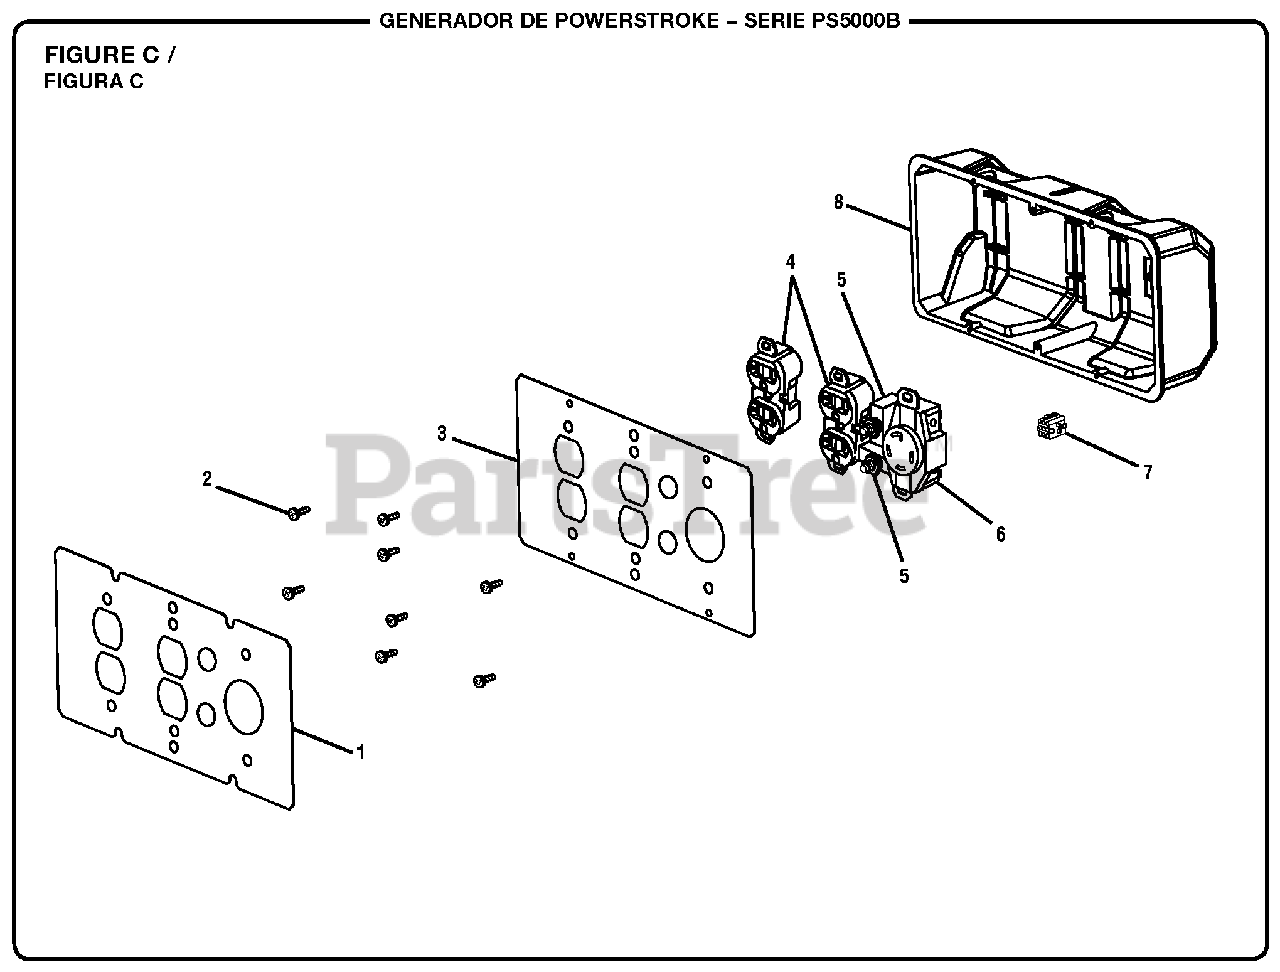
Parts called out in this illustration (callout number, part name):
1	Label (Power Outlet)
3	Front Panel
4	Duplex Receptacle
5	Circuit Breaker, 20 Amp
6	Twist Lock Receptacle
8	Control Box (Back Panel)
